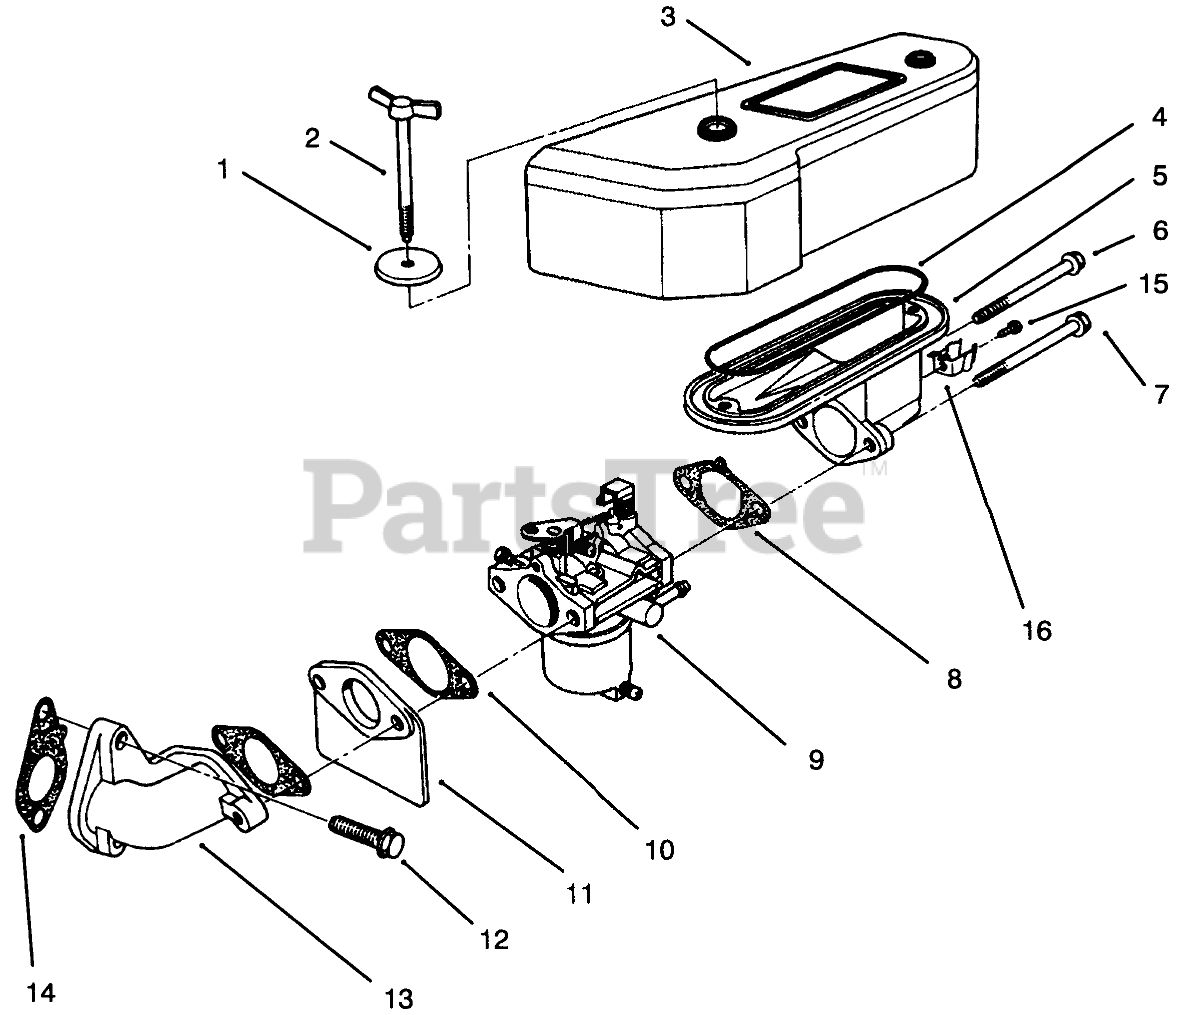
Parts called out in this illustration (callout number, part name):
1	Washer
3	Filter ASM
4	Gasket
5	Pipe-Intake
8	Gasket
9	Carburetor ASM
10	Gasket
12	Bolt-Flanged (8X25)
13	Pipe-Intake
14	Gasket
15	Screw
